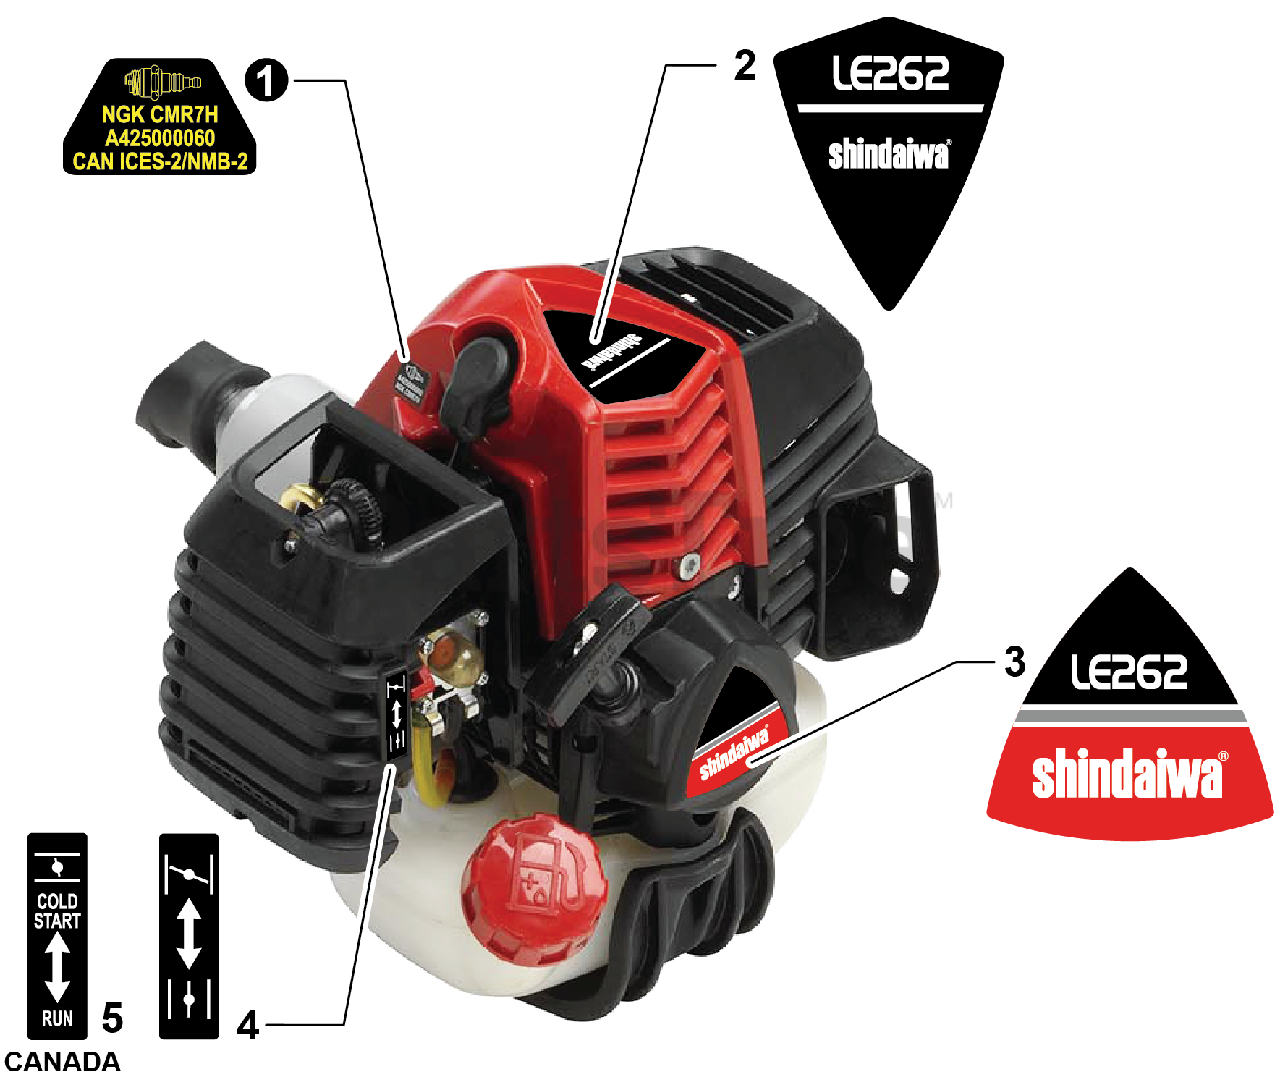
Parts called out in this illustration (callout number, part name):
1	LABEL, SPARK PLUG - CMR7H
2	LABEL - MODEL LE262
3	LABEL, RECOIL STARTER
4	LABEL, CHOKE
5	LABEL, CHOKE
